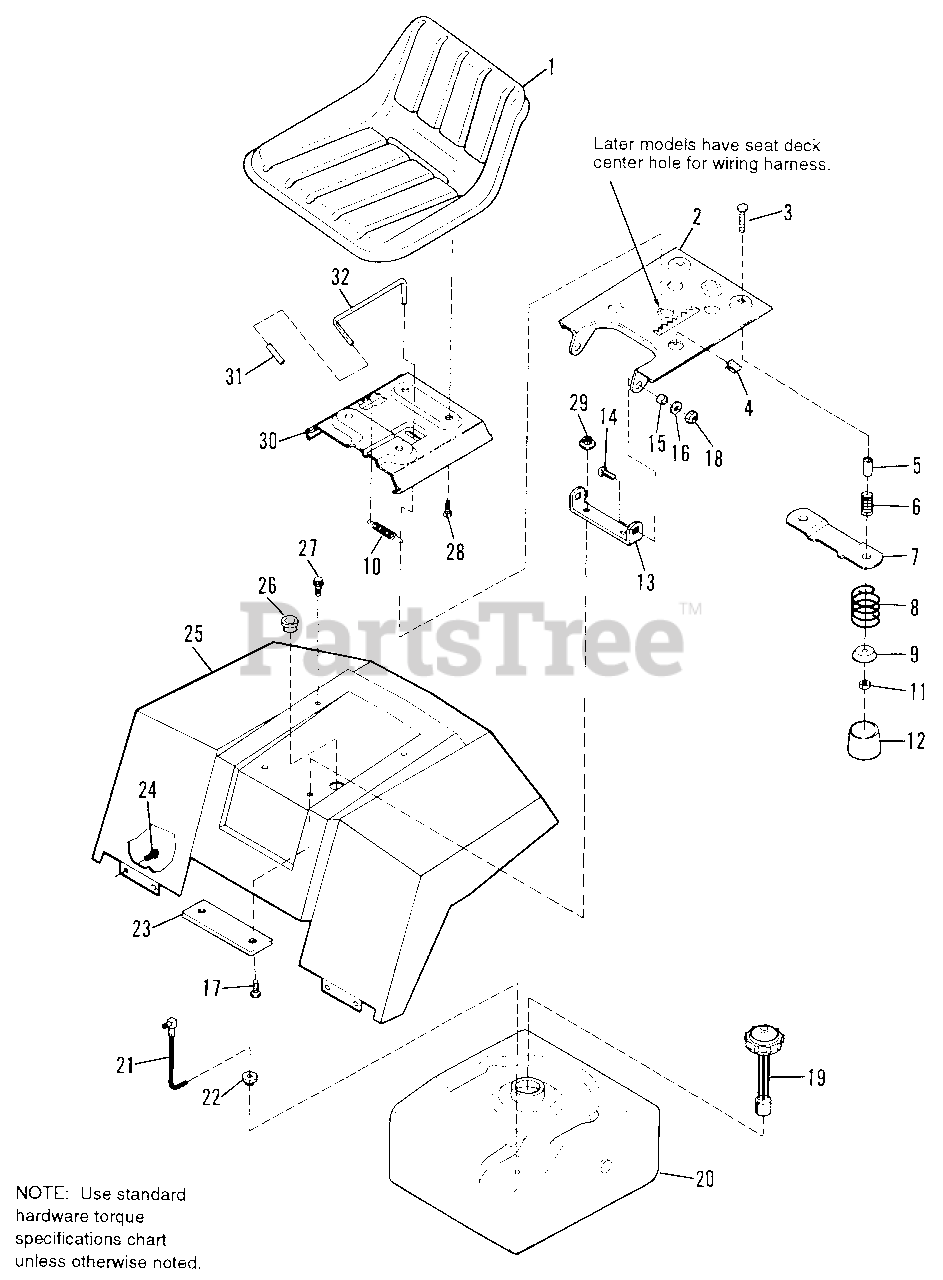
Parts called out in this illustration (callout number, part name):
2	SUPPORT, Seat Pivot (Later models)
2	SUPPORT, Seat Pivot (Early models)
3	CARRIAGE BOLT, 5/16-18 x 2
4	CLIP, Speed
6	SPRING, Compression
7	PLATE, Switch
8	SPRING, Compression
9	WASHER, Plain
10	SPRING, Extension
11	NUT, Hex, Nylon Lock, 5/16-18
12	COVER, Spring
13	BRACKET, Seat Pivot
14	CARRIAGE BOLT, 3/8-16 x 1
16	WASHER, Plain, 13/32
17	SCREW, Truss Hd., Torx drive, 3/8-16 x 1
18	NUT, Hex, Nylon Lock, 3/8-16
19	CAP, Fuel Gauge
20	TANK, Fuel
21	ELBOW & TUBE ASSY.
23	PLATE, Reinforcement
24	SCREW, Taptite, 1/4-20 x 1/2
26	BUSHING, Snap
27	SCREW, Taptite, 5/16-18 X 5/8
28	BOLT, Hex, Whizlock, 5/16-18 x 5/8
29	NUT, Hex, Flange, Whizlock, 5/16-18 x 1/2
30	BRACKET, Seat Slide
31	HANDLE, Grip
32	LEVER, Seat Release
